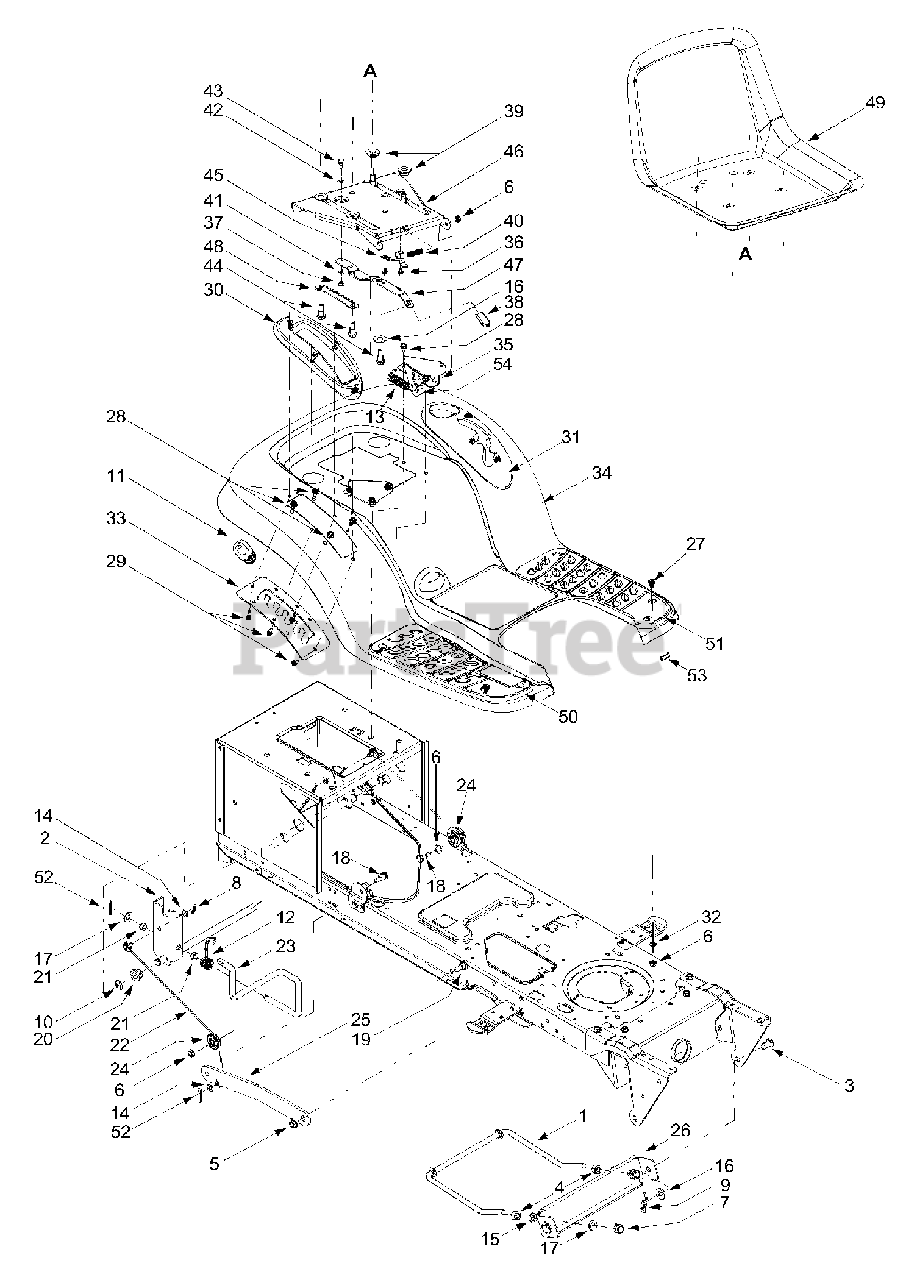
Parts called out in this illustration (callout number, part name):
3	Clevis Pin, .5 x .78
4	Hex Nut, 1/2-13
5	Flange Lock Nut, 3/8-16
6	Flange Lock Nut, 5/16-18
7	Hex Nut, 1/2-13
8	Internal Cotter Pin
9	Internal Cotter Pin
10	E-ring
11	Handle Grip
12	Torsion Spring
13	Extension Spring, .872 x 3.4
14	Flat Washer, 5/16
15	Lock Washer, 1/2
16	Flat Washer, .31 x 1.062 x .134
17	Flat Washer, .51 x 1.12 x .06
18	Hex Cap Screw, 5/16-18 x .62
19	Shoulder Screw, 3/8-16
20	Hex Flange Bearing
21	Snap Flange Bearing
22	Lift Cable, 16.16
23	Lift Handle
24	Roller Pulley
27	Carriage Bolt, 5/16 x .62
28	Self-tapping Screw, 5/16-18 x .625
29	Self-tapping Screw, 1/4-15 x .75
30	Lift Lever Cover
31	Shift Lever Cover w/ Cup Holder
32	Flat Washer, .349 x 1.0 x .063
36	Screw, #10-16 x .375
37	Hex Flange Lock Nut, 1/4-20
38	Seat Adjuster Grip
39	Spacer
40	Compression Spring, .41 x 1.5
41	Spring Washer, .265 x .562 x .025
42	Flat Washer, .344 x .62 x .03
43	Shoulder Screw, .340 x .285,1/4-20
44	Shoulder Screw, .50 x .50, 3/8-16
45	Seat Stop
48	Seat Adjustment Selector
49	Medium Back Seat, Yellow
50	RH Foot Pad
51	LH Foot Pad
52	Cotter Pin
53	Trim Strip
54	Seat Lift Bracket
